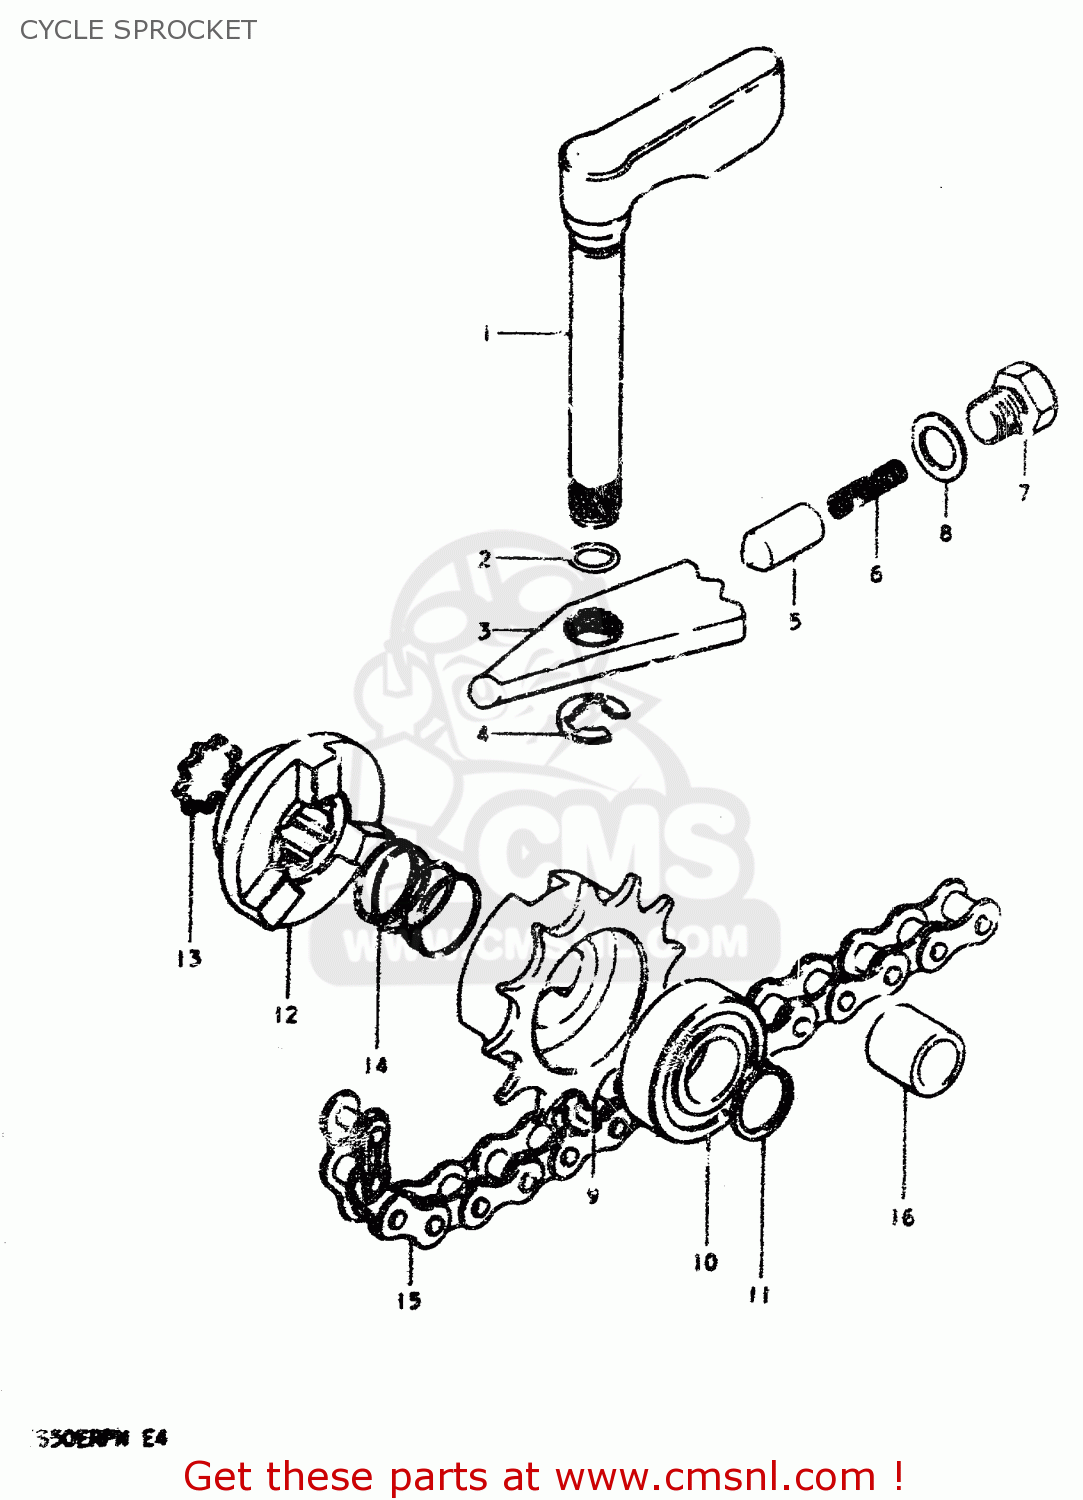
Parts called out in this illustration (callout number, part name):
1	LEVER, SPROCKET SHIFTING
2	O RING(D:1.3,ID:7.6)
3	ARM, SPROCKET SHIFTING
4	E RING
5	STOPPER
6	SPRING
7	BOLT 10X9
8	WASHER
9	SPROCKET, CYCLE (NT:12)
10	BEARING
11	CIRCLIP,15MM
12	WHEEL
13	RING,ENGINE SPROCKET
14	SPRING
15	CHAIN, CYCLE (48L)
16	HOSE
